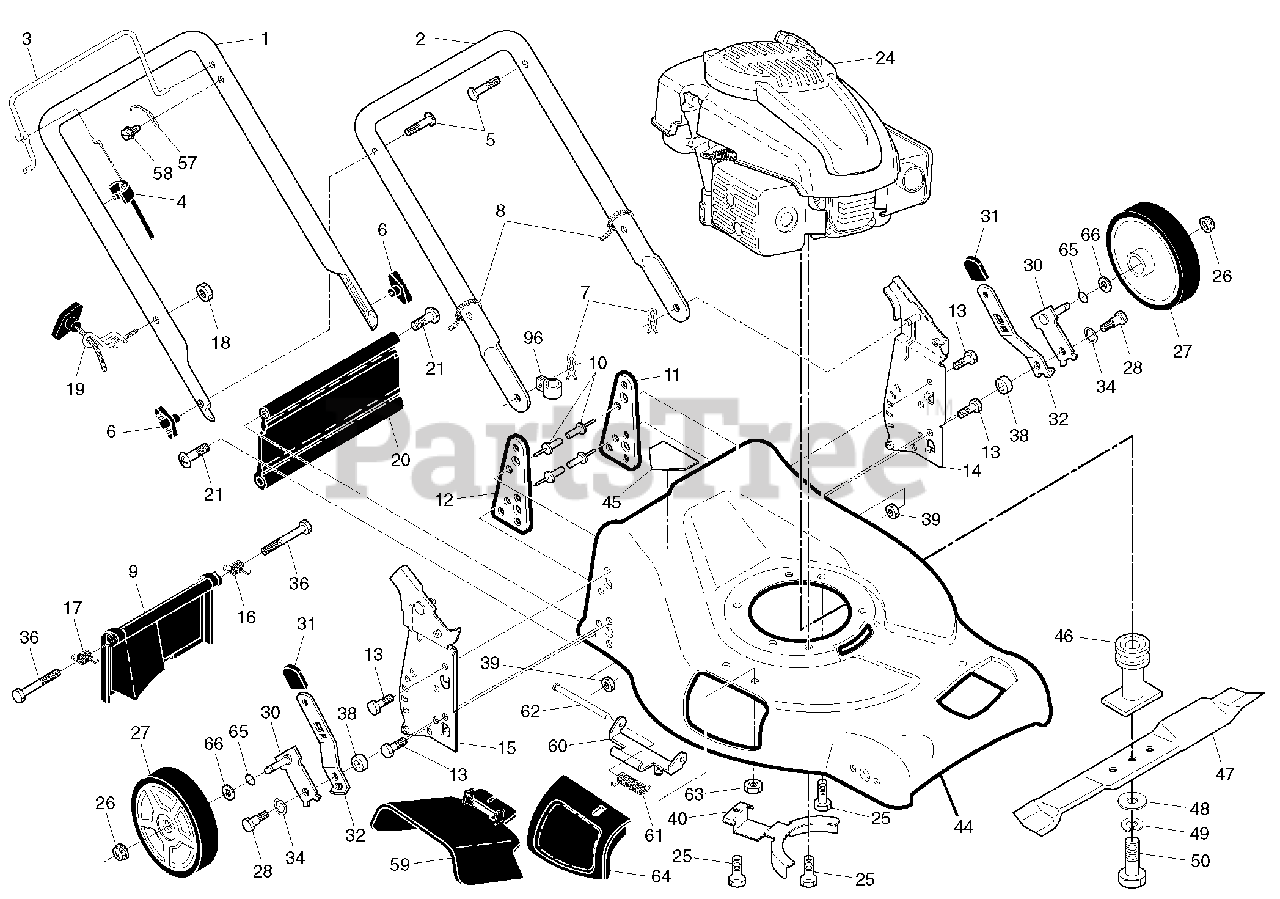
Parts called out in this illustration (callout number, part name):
1	Upper Handle
2	Lower Handle
3	Control Bar
4	Engine Zone Control Cable
5	Handle Bolt
6	Handle Knob
7	Hairpin Cotter
8	Wire Tie
9	Rear Door Assembly
10	Pop Rivet
11	Support Bracket, LH
12	Support Bracket, RH
13	Screw 1/4-20 x 5/8
14	Handle Bracket Assembly, LH
15	Handle Bracket Assembly, RH
16	Spring, Rear Door, LH
17	Spring, Rear Door, RH
18	Keps Locknut 1/4-20
19	Rope Guide
20	Rear Skirt
21	Hinge Screw 1/4-20 x 1-1/4
25	Screw, Hex Head, Thread Rolling 3/8-16 x 1-1/8
26	Hex Flange Nut
27	Wheel & Tire Assembly
28	Shoulder Bolt 5/16-18 x .33
30	Axle Arm Assembly, Rear
31	Selector Knob
32	Selector Spring
34	Washer, Curved, Cylindrical
36	Bolt
38	Spacer
39	Nut, Hex
44	Kit, Lawn Mower Housing
45	Danger Decal
46	Blade Adapter / Pulley
47	Blade, 21"
48	Hardened Washer
49	Helical Washer
50	Hex Head Machine Screw 3/8-24 x 1-3/8 Grade 8
57	Upstop Bracket
58	Screw
59	Discharge Deflector
60	Hinge Bracket
61	Spring
62	Rod, Hinge
63	Nut, Hex
64	Mulcher Door
65	O-Ring
66	Washer, Flat 1/2
96	Clip, Cable
